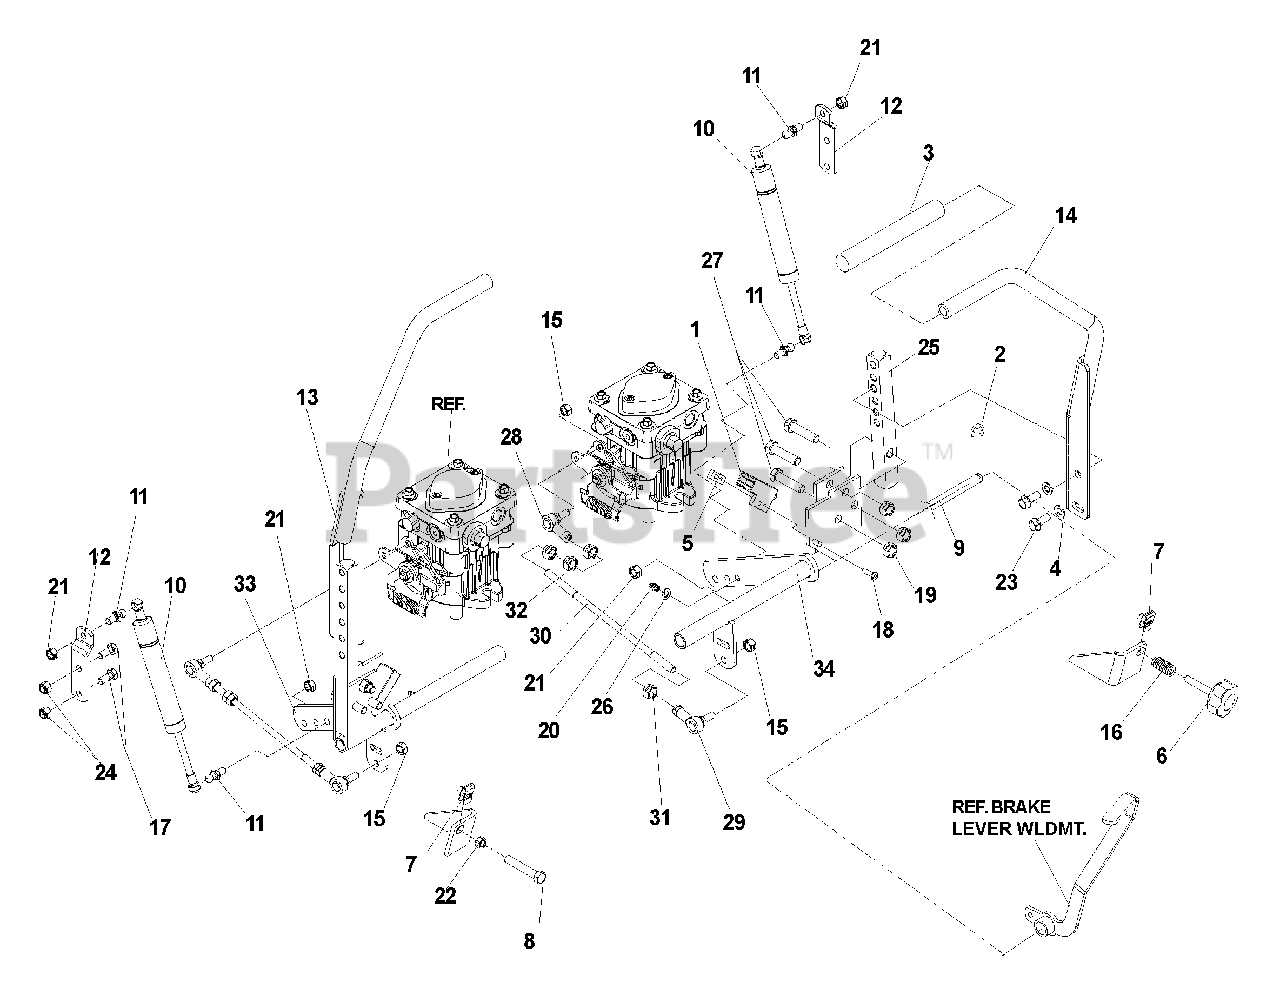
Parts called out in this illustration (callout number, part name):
1	SWITCH, INTERLOCK
2	E-RING, 1/2
3	CUSHION, DRIVE LEVER
4	WASHER, 3/8, SPRING, SPEC
5	NUT, #10-24
6	ADJUSTMENT KNOB
7	NUT, 5/16-18, U-TYPE, RETAINER
8	HCS, 5/16-18 X 1 3/4, TPBLT, GR5
9	CONTROL SHAFT
10	DAMPENER
12	DAMPENER ARM
13	DRIVE LEVER, RIGHT
14	DRIVE LEVER, LEFT
15	NUT, 5/16, NYLOC
16	COMPRESSION SPRING
17	HCS, 5/16-18 X 3/4, GR5
18	SCREW, #10-24 X 5/8, COMBO, SPEC
19	NUT, 3/8-16, NYLOC
20	ZERK, STRAIGHT, 1/4-28
21	NUT, 5/16-18, CENTERLOCK
22	NUT, 5/16-18
23	HCS, 3/8-16 X 1, GR5
24	NUT, 5/16-18, NYLOC
25	ARM CONTROL SHAFT
27	HCS, 3/8-16 X 1 3/4, GR5
28	ROD END, SPHERICAL, RIGHT
29	ROD END, SPHERICAL, LEFT
31	NUT, 5/16, JAM, LH
33	DRIVE CONTROL, RIGHT
34	DRIVE CONTROL, LEFT
